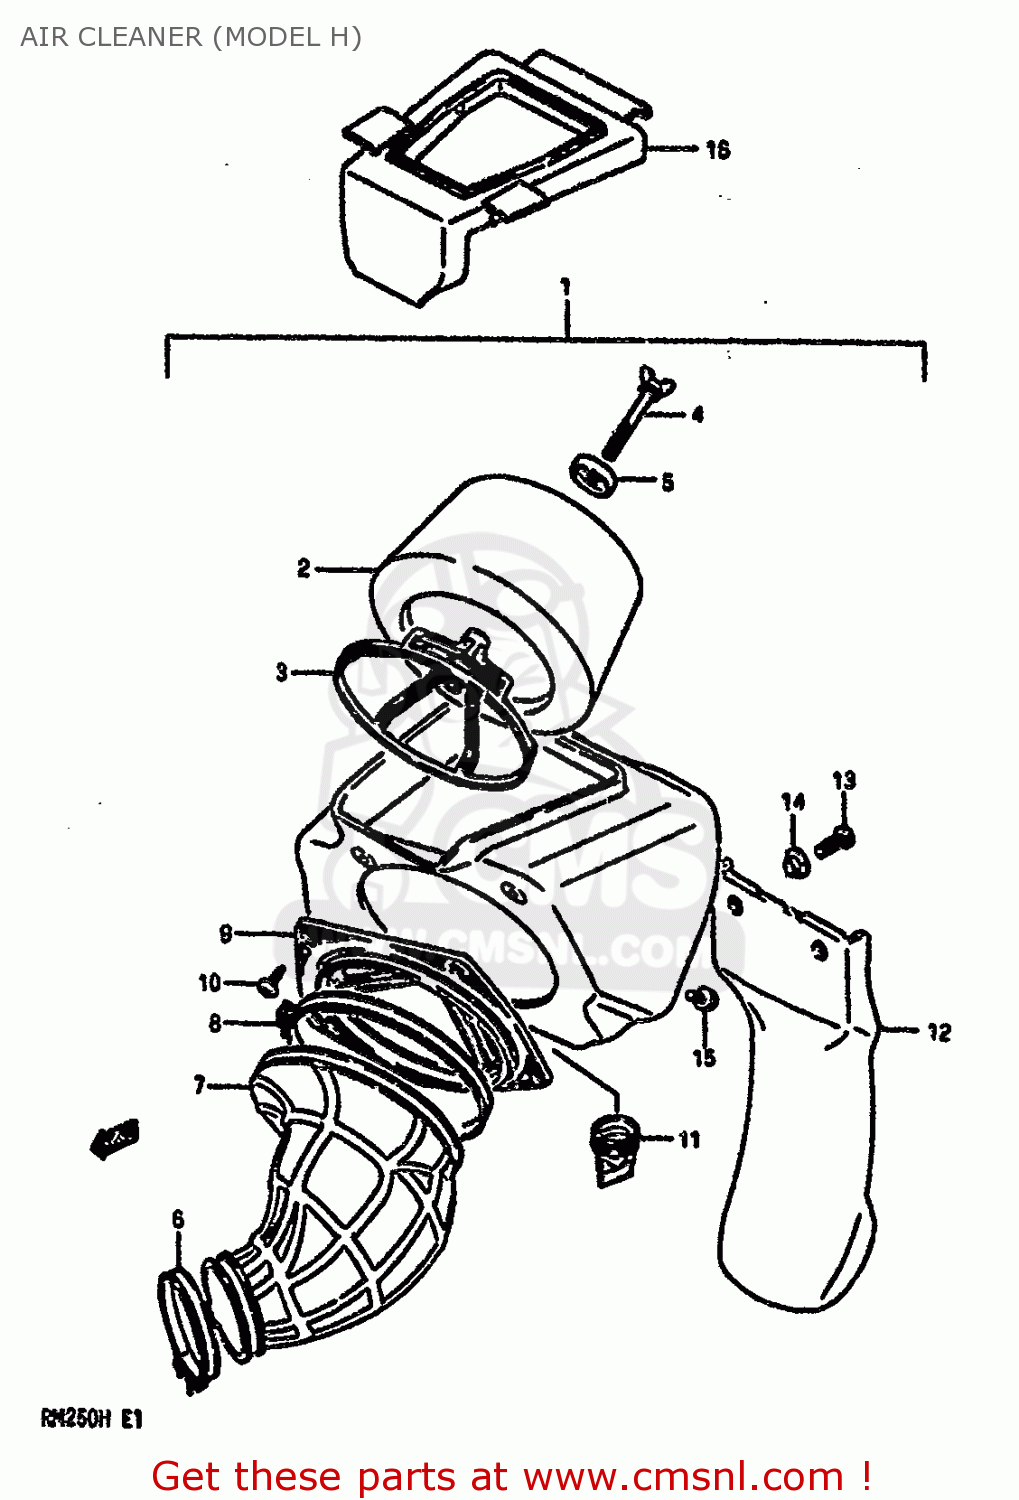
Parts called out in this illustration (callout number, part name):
1	CLEANER ASSEMBLY,AIR
2	FILTER,AIR CLEANER
3	HOLDER,FILTER
4	BOLT,WING
5	WASHER,AIR CLEANER
6	CLAMP
7	TUBE,AIR CLEANER OUTLET
8	CLAMP
9	HOLDER,FILTER
10	SCREW
11	HOSE,AIR CLEANER DRAIN
12	GUARD,MUD
13	SCREW
14	COLLAR
15	BOLT 6X12
16	GUARD,MUD
